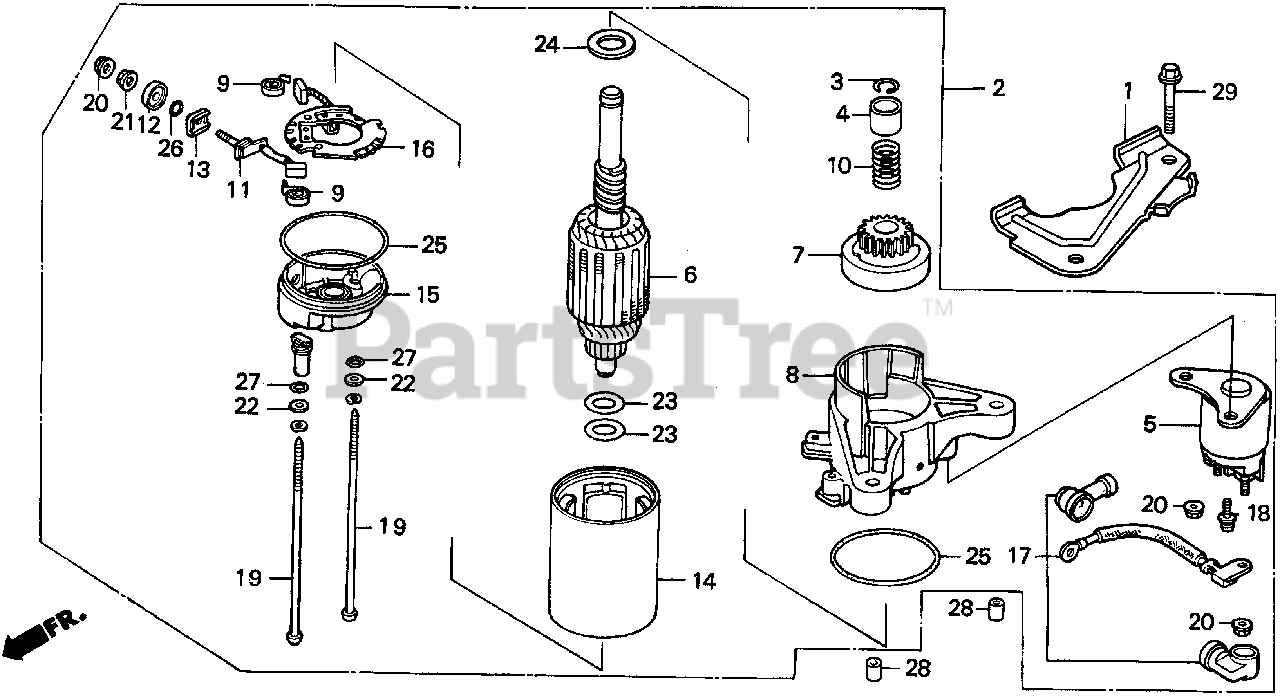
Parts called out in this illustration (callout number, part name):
1	PLATE, SIDE
2	MOTOR ASSY., STARTER
3	RING, SNAP
4	COLLAR, CLUTCH
5	CONTACTOR ASSY.
6	ARMATURE
7	CLUTCH, OVERRUNNING
8	HOUSING, DRIVE SIDE
9	SPRING, BRUSH
10	SPRING
11	BRUSH
12	BUSHING, INSULATION
13	BUSHING, INSULATION
14	YOKE
15	FRAME, STARTER END
16	PLATE, BRUSH HOLDER
17	WIRE, WATER COVER
18	SCREW-WASHER (5X14)
19	BOLT, THROUGH (Honda Code 1412428). (NOT AVAILABLE)
19	BOLT, THROUGH
20	NUT
21	NUT
22	WASHER, STEEL PLATE
23	WASHER
24	WASHER
25	O-RING
26	O-RING
27	O-RING
28	PIN A, DOWEL (10X16)
29	BOLT, FLANGE (8X35)
